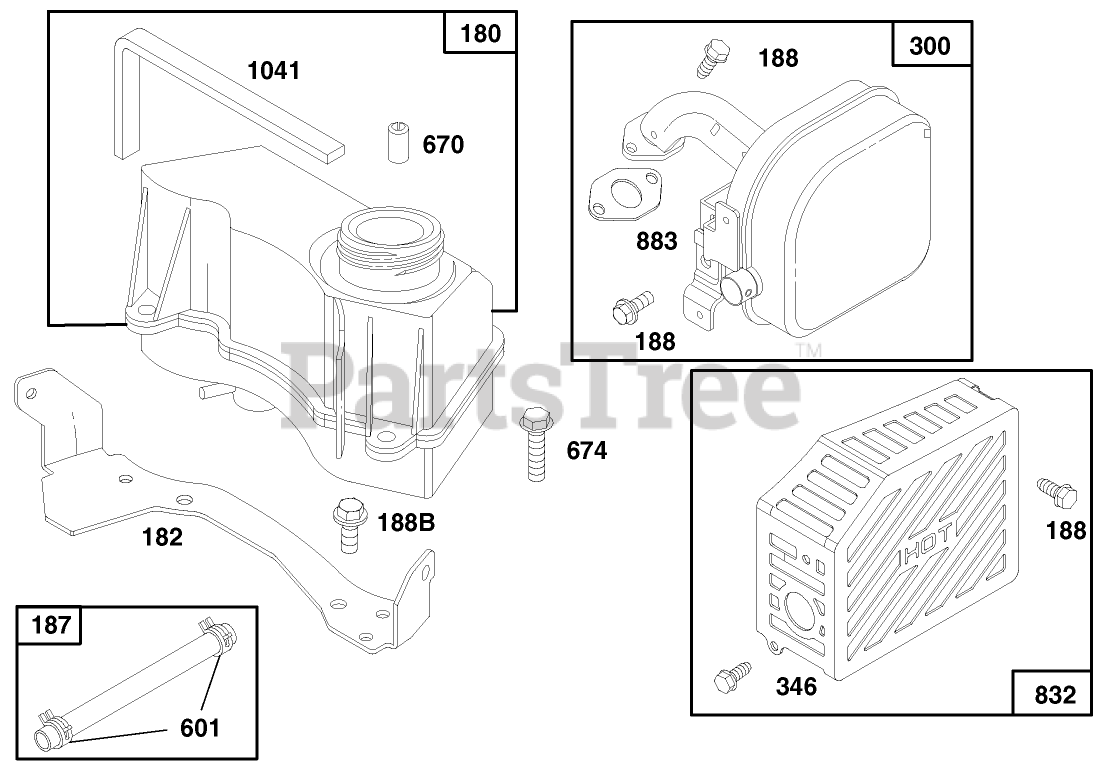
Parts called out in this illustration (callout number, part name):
180	TANK ASSY - FUEL
187	BRIGGS 296004
300	MUFFLER - EXHAUST
670	SPACER
674	SCREW - HEX HEAD
